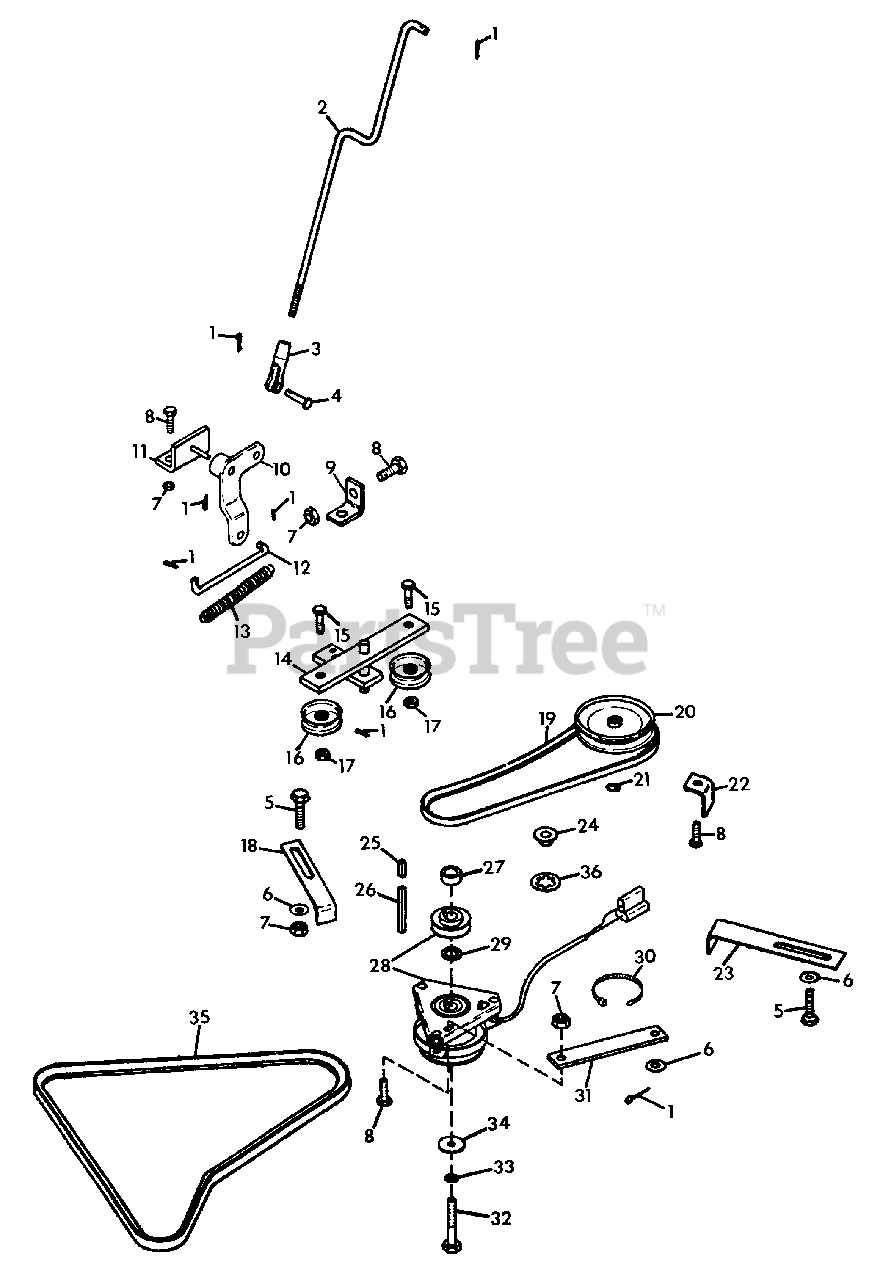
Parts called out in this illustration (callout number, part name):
1	PIN, COTTER .09X.625
2	ROD, NEUTRAL CLUTCH
3	CLEVIS, 3/8-24
4	PIN, CLEVIS .312X.812
5	BOLT, HEX 5/16-18X1.75
6	WASHER, FLAT .344X.688X.065
7	NUT, LOCK 5/16-18
8	BOLT, HEX 5/16-18X.75
9	TAB, SPRING
10	LEVER, CLUTCH PIVOT
11	WELDMENT, CLUTCH LEVER BRACKET
12	ROD, CLUTCH IDLER ACTUATING
13	SPRING, NEUTRAL CLUTCH
14	WELDMENT, CLUTCH IDLER ACTUATING
15	BOLT, HEX 3/8-16X1.25
16	SHEAVE, IDLER
17	NUT, LOCK 3/8-16
18	BELT GUIDE, FRONT CLUTCH HUB
19	BELT, TRANSMISSION
20	SHEAVE, TRANSMISSION
21	RING, RETAINING
22	BELT GUIDE, TRANSMISSION
23	BELT GUIDE, REAR CLUTCH HUB
24	BUSHING, NYLON
25	KEY, SQUARE
26	KEY, RECTANGULAR
27	SPACER, ELECTRIC CLUTCH
28	CLUTCH, ELECTRIC
29	SPACER, ELECTRIC CLUTCH
30	TIE, CABLE
31	BRACE, PTO CLUTCH
32	BOLT, HEX 7/16-20X3.0
33	WASHER, LOCK 7/16 REG.
34	WASHER, SPECIAL FLAT
35	BELT, MOWER
36	RING, RETAINING
